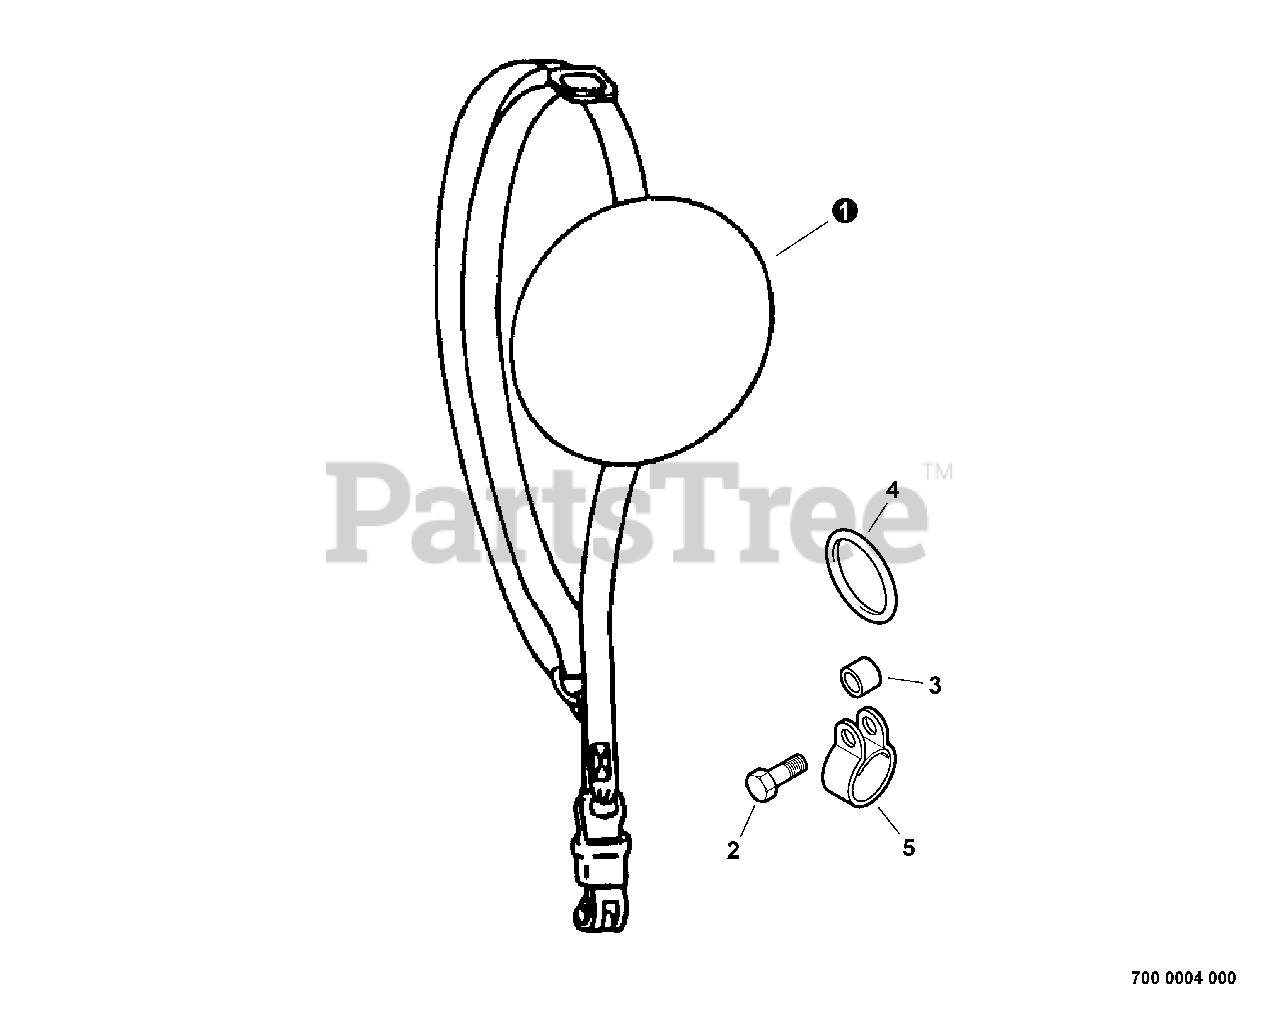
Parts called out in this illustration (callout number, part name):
1	HARNESS, SHOULDER
2	BOLT 5×18
3	SPACER, GUARD
4	RING, HARNESS Ø32
